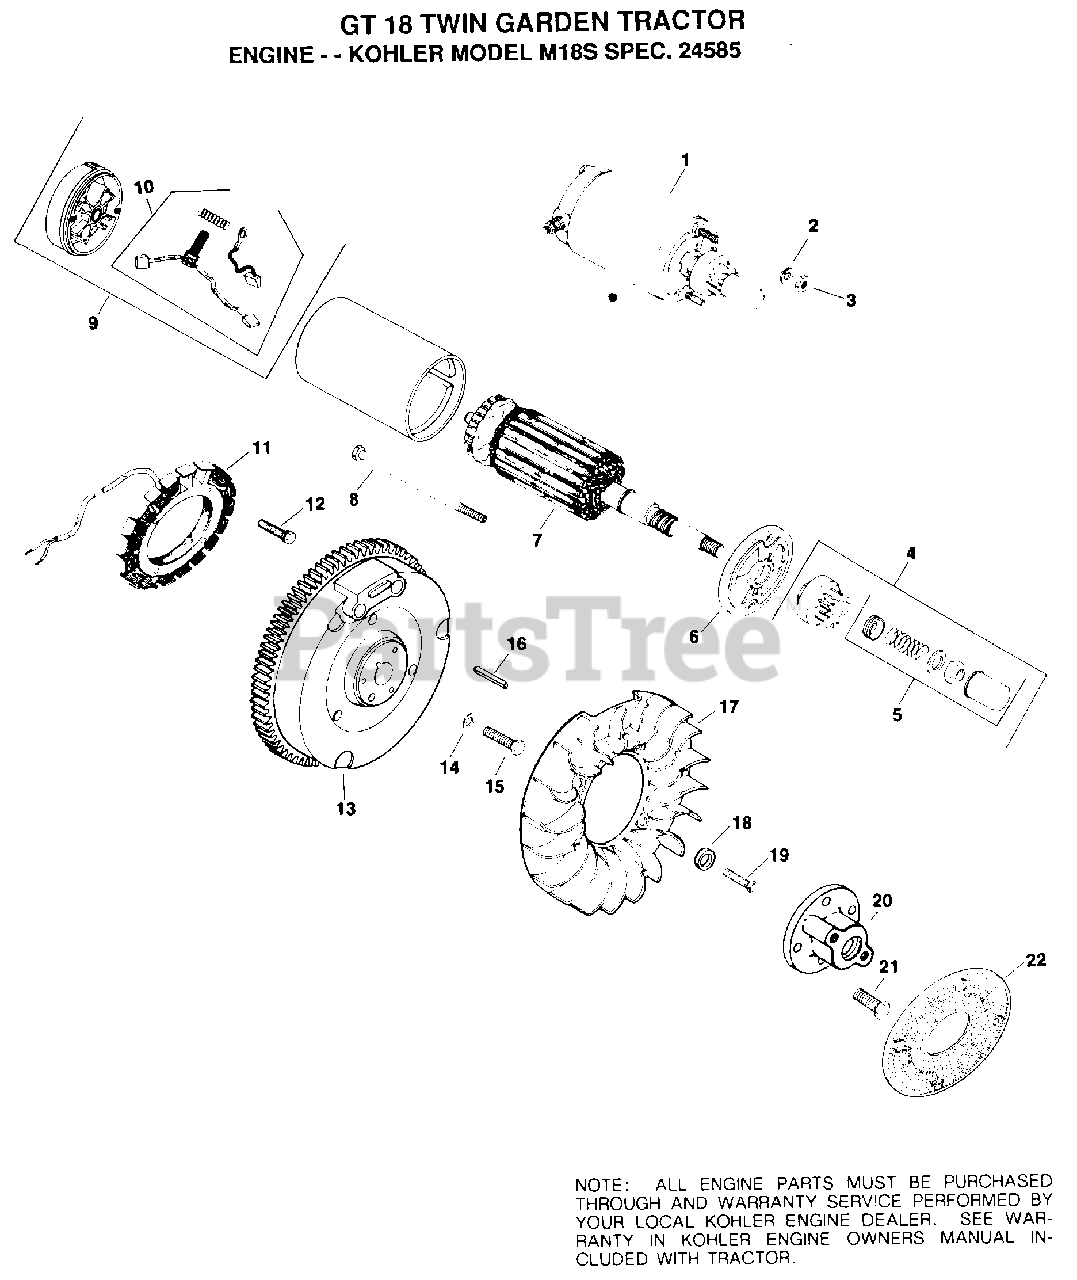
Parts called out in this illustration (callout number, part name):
2	WASHER
3	NUT
5	KIT, DRIVE PARTS
6	CAP, DRIVE END
9	CAP, COMMUTATOR END
11	KIT
12	SCREW
15	SCREW, 3/8-24X1-1/4
16	KEY
19	SCREW, HEX 1/4-20 X 5/8
20	SHAFT, FRONT DRIVE
21	SCREW
22	SCREEN, GRASS
